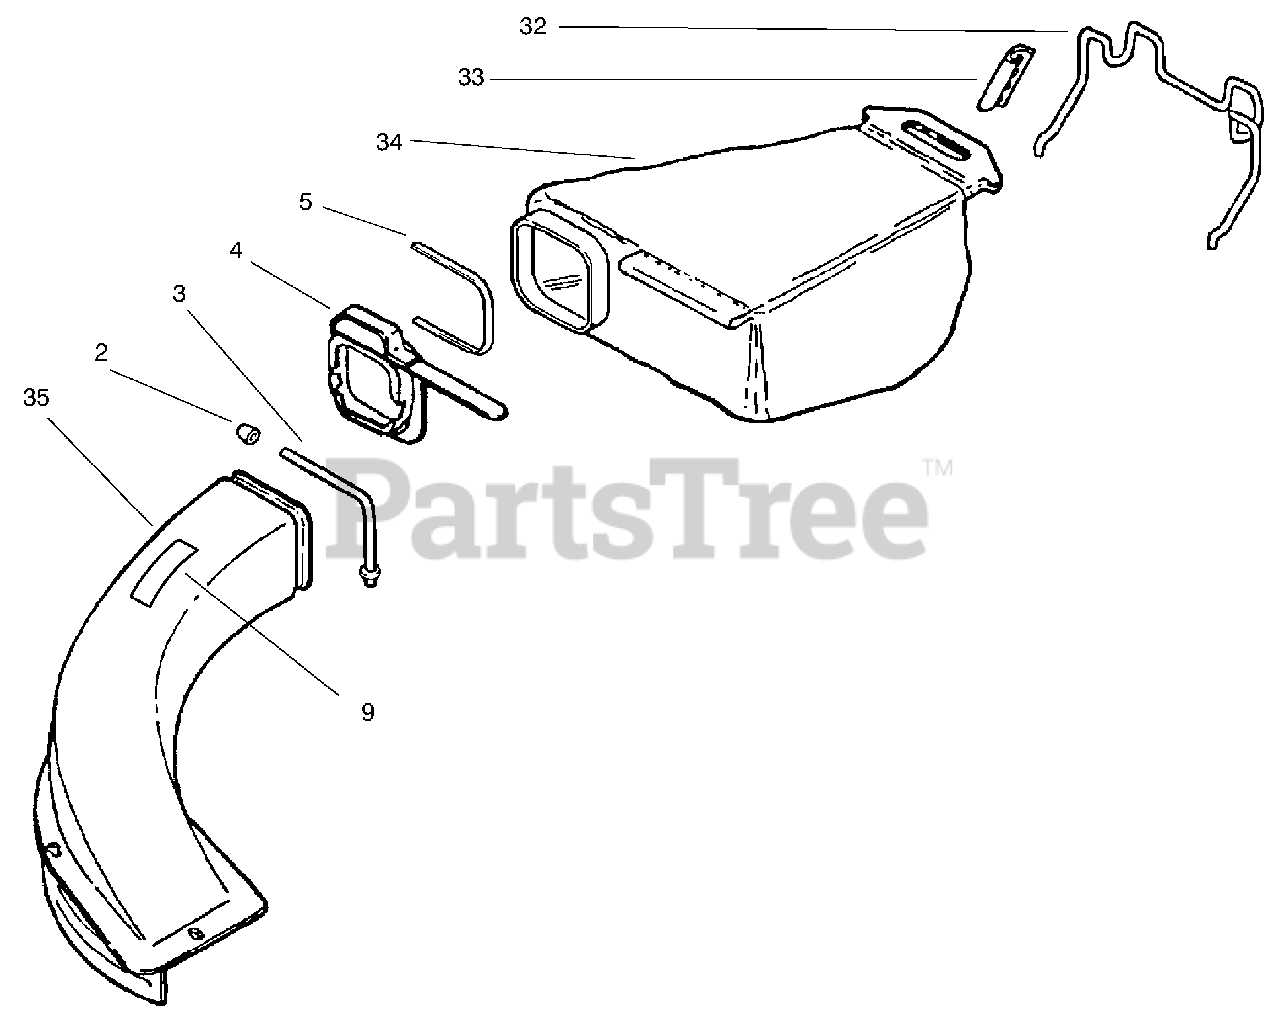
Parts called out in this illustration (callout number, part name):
2	Nut-Cap
3	Support-Chute
4	ASM-Adaptor
5	Tie Strap
9	Decal-Danger
32	Hanger-Wire
33	Hanger-Clamp
34	ASM-Bag & Adapter
35	ASM-Chute & Support
